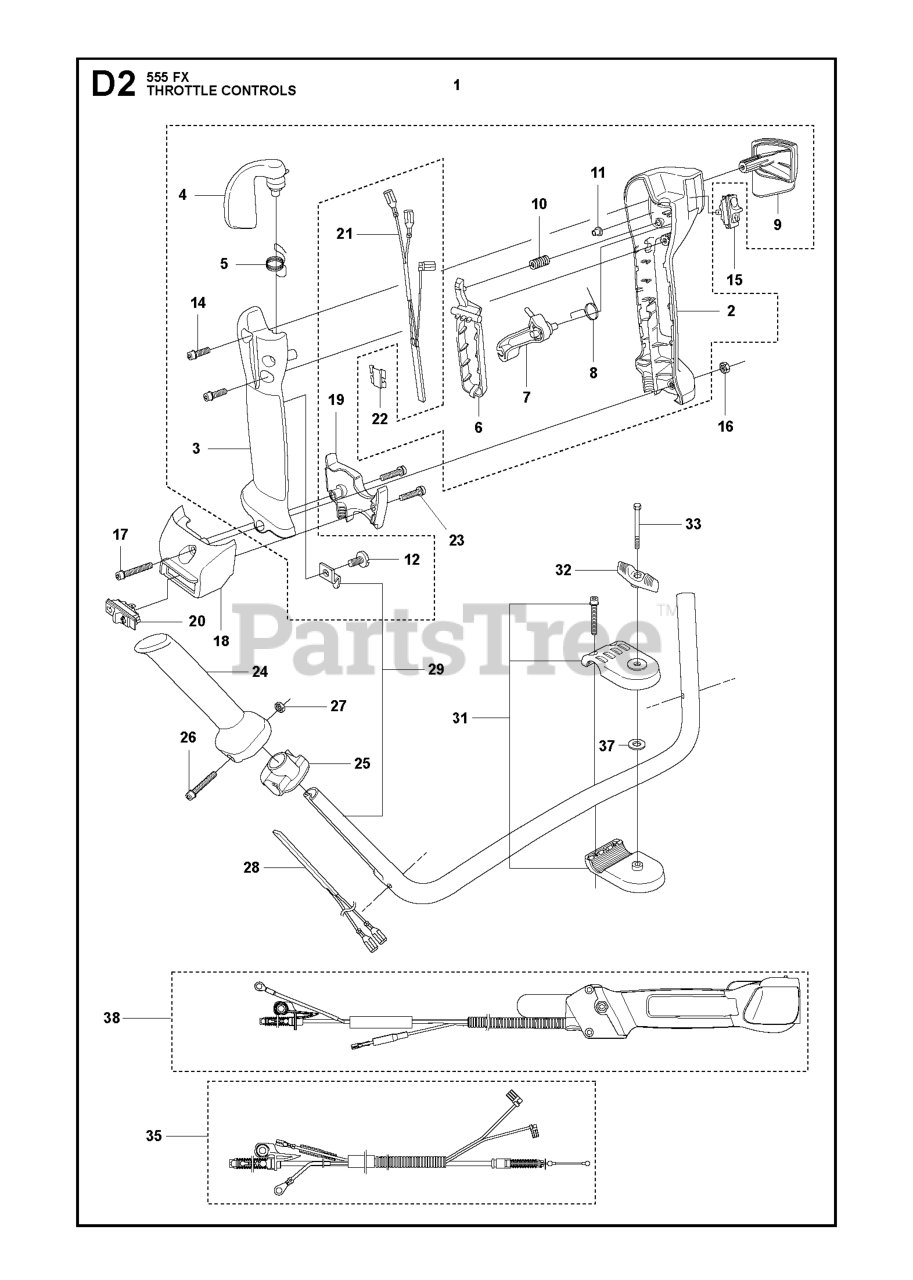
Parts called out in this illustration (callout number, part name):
1	THROTTLE HANDLE
2	HANDLE
3	HANDLE
4	THROTTLE TRIGGER
5	RP SPRING
6	THROTTLE LOCK
7	LEVER
8	SPRING
9	COVER
10	SPRING
11	SLEEVE
12	SCREW
13	HOLDER
14	SCREW
15	STOP BUTTON
16	NUT M6M M5
17	SCREW
18	HOLDER
19	HOLDER
20	SWITCH (G)
21	HEATING ELEMENT
23	SCREW
27	NUT M6M M5
28	HEATING ELEMENT
29	%HANDLE
30	HANDLE HOLDER LOWER
31	HANDLE HOLDER UPPER
35	WIRING
